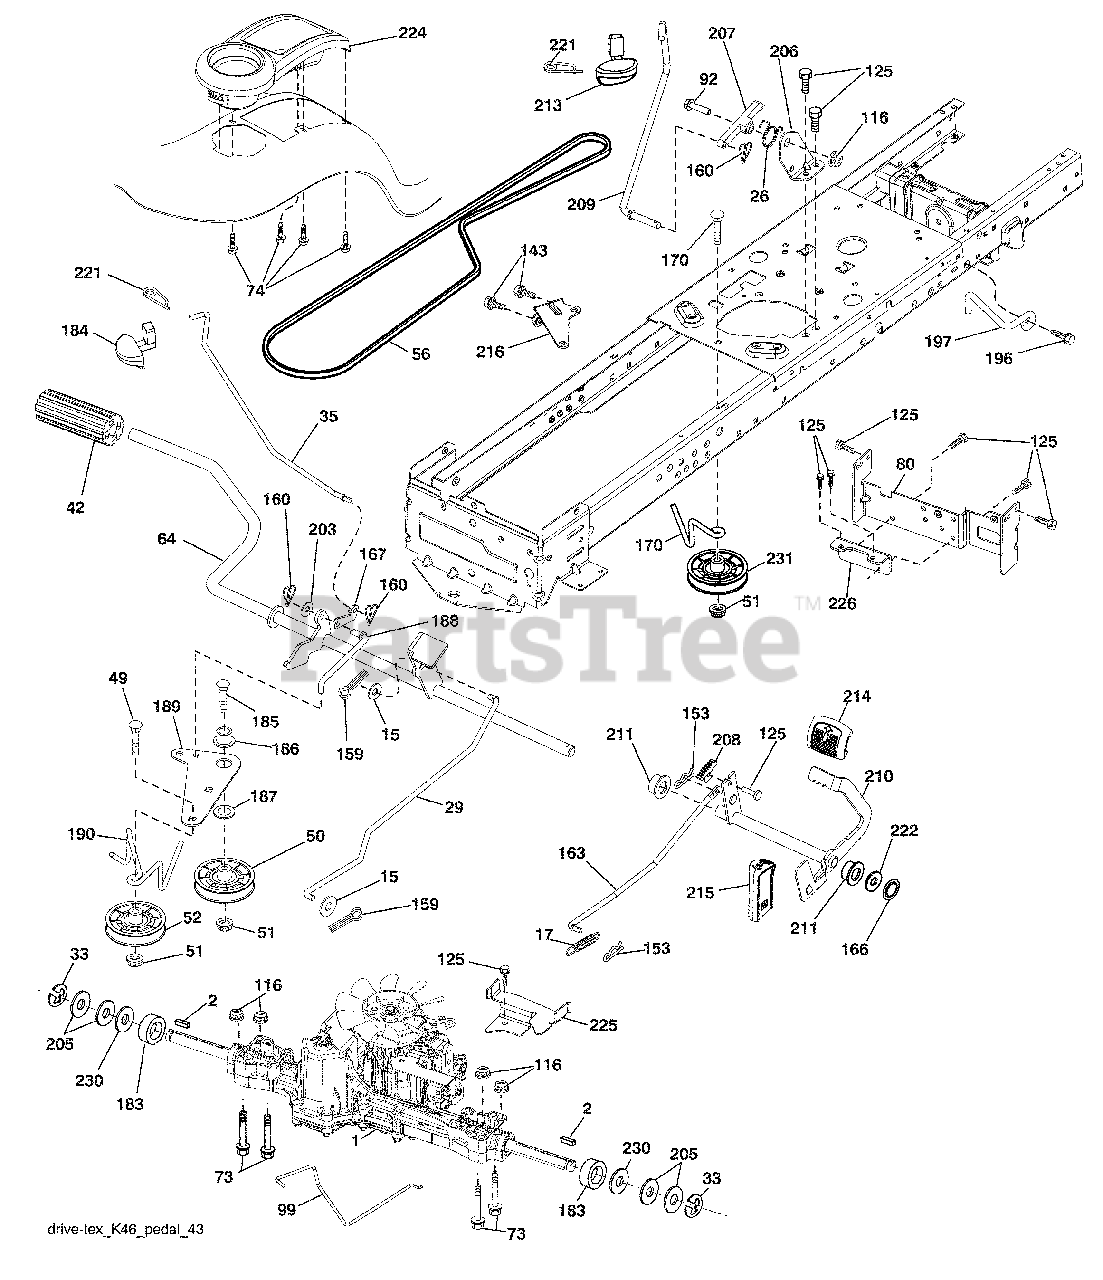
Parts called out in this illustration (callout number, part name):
1	Transaxle, TUFFTORQ K46 BT
2	Key 1/4 x 2.5
15	Washer 13/32 x 13/16 x 16 Ga.
17	Spring, Brake
26	Spring Return Cruise
29	Rod, Brake
35	Rod, Brake, Park
42	Cover, Foot Pedal
50	Pulley Idler Flat
51	Lock Nut 3/8-16
52	Idler V-Groove 910" Offset
56	Belt, Drive
64	Shaft Asm. Pedal Brake Control
70	Console Asm.
73	Bolt Hex Flghd. 5/16-18 x Gr. 5
74	Screw 1/4 x 1/2
80	Bracket Strap Torque
92	Bolt Fin. Hex 5/16-18 unc x 1.25
99	Rod Bypass
116	Nut Lock Hex Flange 5/16-18
125	Screw 5/16-18 x 3/4
143	Screw 5/16-18 x 1/2
153	Retainer Spring
159	Pin Cotter 1/8 x 3/4
160	Retainer Clip
161	Spring, Return, Clutch
163	Rod Pedal Control
166	Nut Push .625
167	Latch Brake Parking
170	Keeper Belt Centerspan
183	Spacer Split
184	Handle Parking Brake
185	Bolt Rdhd. Sqnk. 3/8-16 unc x 2 - 3/4
186	Spacer Retainer
187	Washer
188	Link Clutch Ground Drive
189	Bellcrank Ground Drive
190	Keeper Bellcrank Ground Drive
196	Screw 3/8-16 x 1
197	Link Clutch Anti-Rotation
206	Bracket Mount Latch Cruise
207	Latch Control Cruise
208	Gear Sector Control Cruise
209	Rod Control Cruise
210	Rocker Asm. Pedal Control
211	Bearing Nylon
213	Knob Control Cruise
214	Pedal Forward Pad
215	Pedal Reverse
216	Bracket Pulley Idler
220	Reflector RH
221	Retainer Spring Clip Handle
222	Washer 21/32 x 1-1/4 x 10 Ga.
224	Console Toolbox
225	Keeper Belt Trans.
226	Bracket Mount Torque
230	Washer Hardened
231	Idler V-Groove
